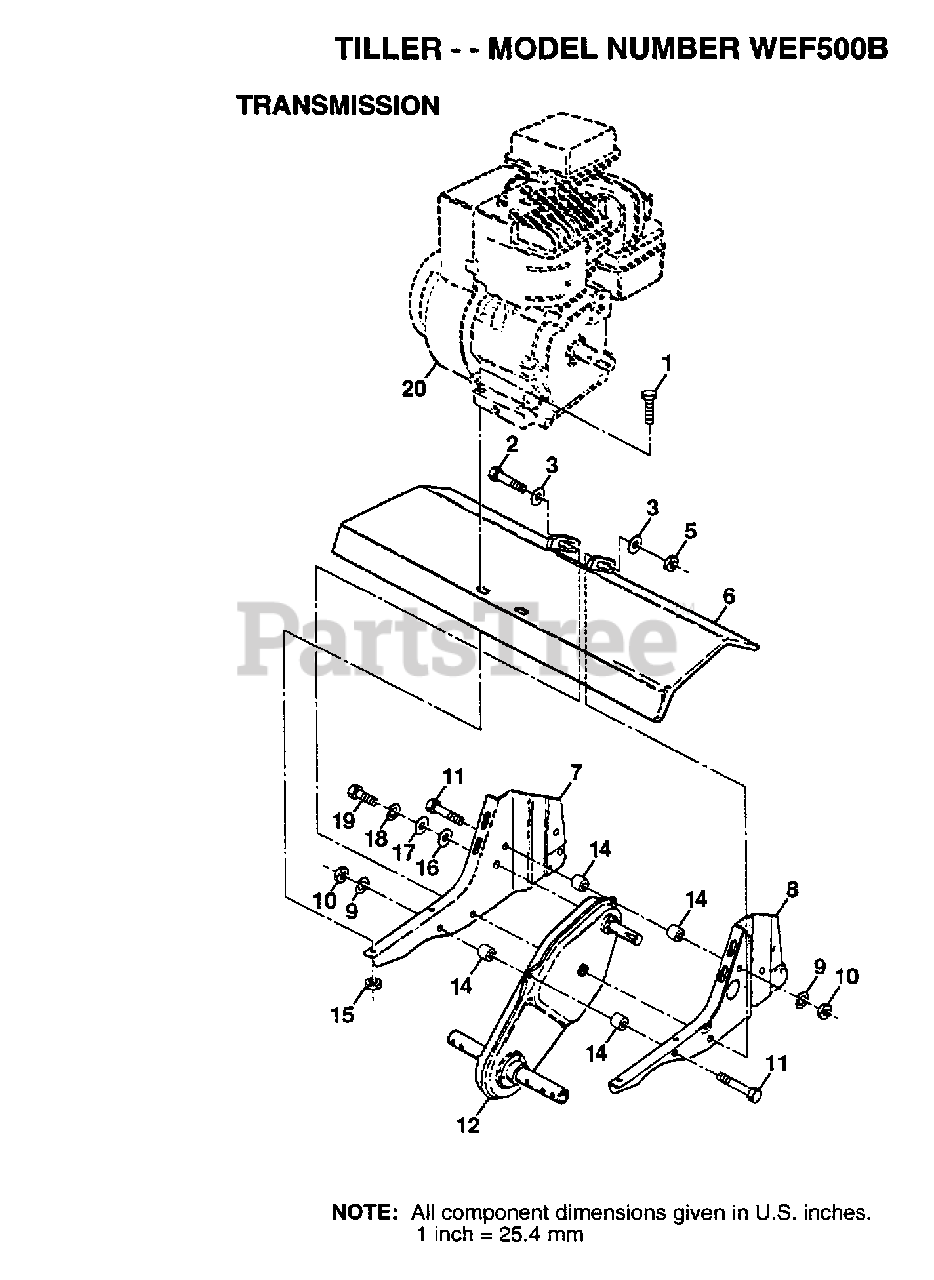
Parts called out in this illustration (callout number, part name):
1	BOLT.HEX.5/16-1.5
2	BOLT HEX 3/8-16
3	WASHER
5	NUT
6	SHIELD.PNT.TINE
9	LOCKWASHER
10	NUT.HEX.5/16-18
14	SPLIT SPACER RT
16	WASHER
17	WASHER
18	LOCKWASHER
19	BOLT
